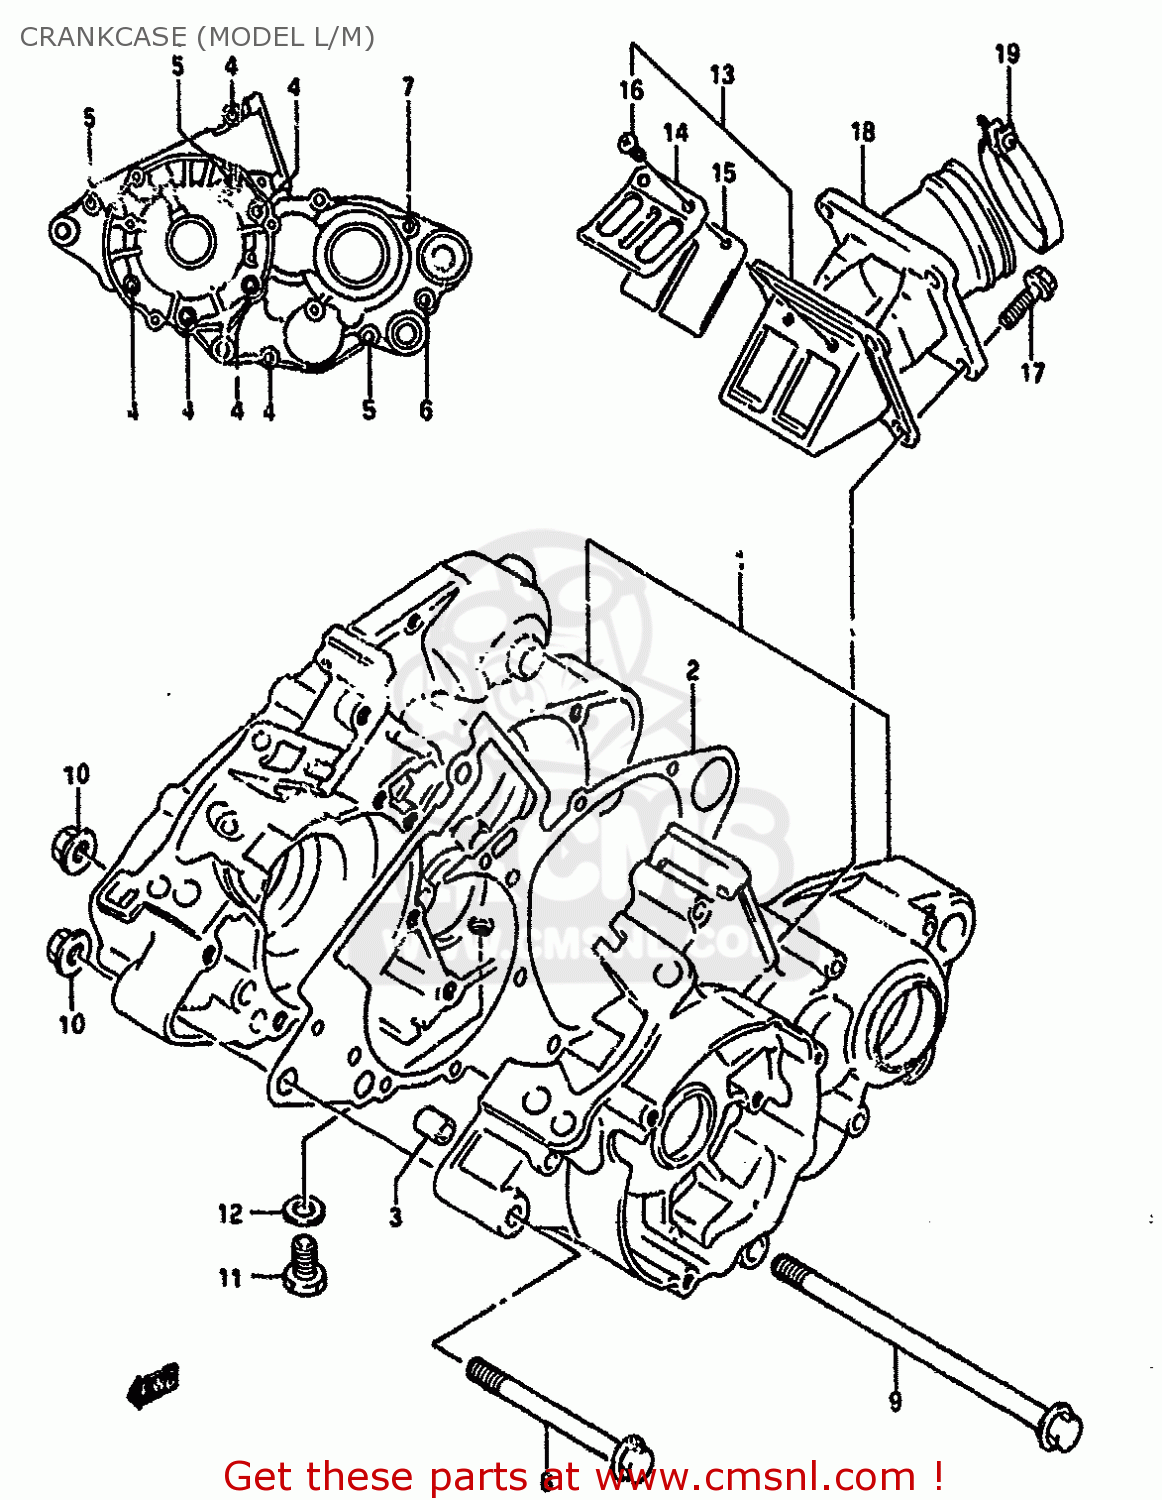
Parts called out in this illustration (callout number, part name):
1	CRANKCASE SET
2	GASKET,CRANKCASE (NAS)
3	PIN
4	BOLT
5	BOLT
6	BOLT
7	BOLT
8	BOLT(8X88)
9	BOLT
10	NUT
11	BOLT,8X16
12	GASKET 8.2X14X1 (NAS)
13	VALVE ASSEMBLY,REED
14	STOPPER,REED VALVE
15	VALVE,REED
16	SCREW
17	BOLT
18	PIPE,INTAKE
19	CLAMP
21	CLAMP
